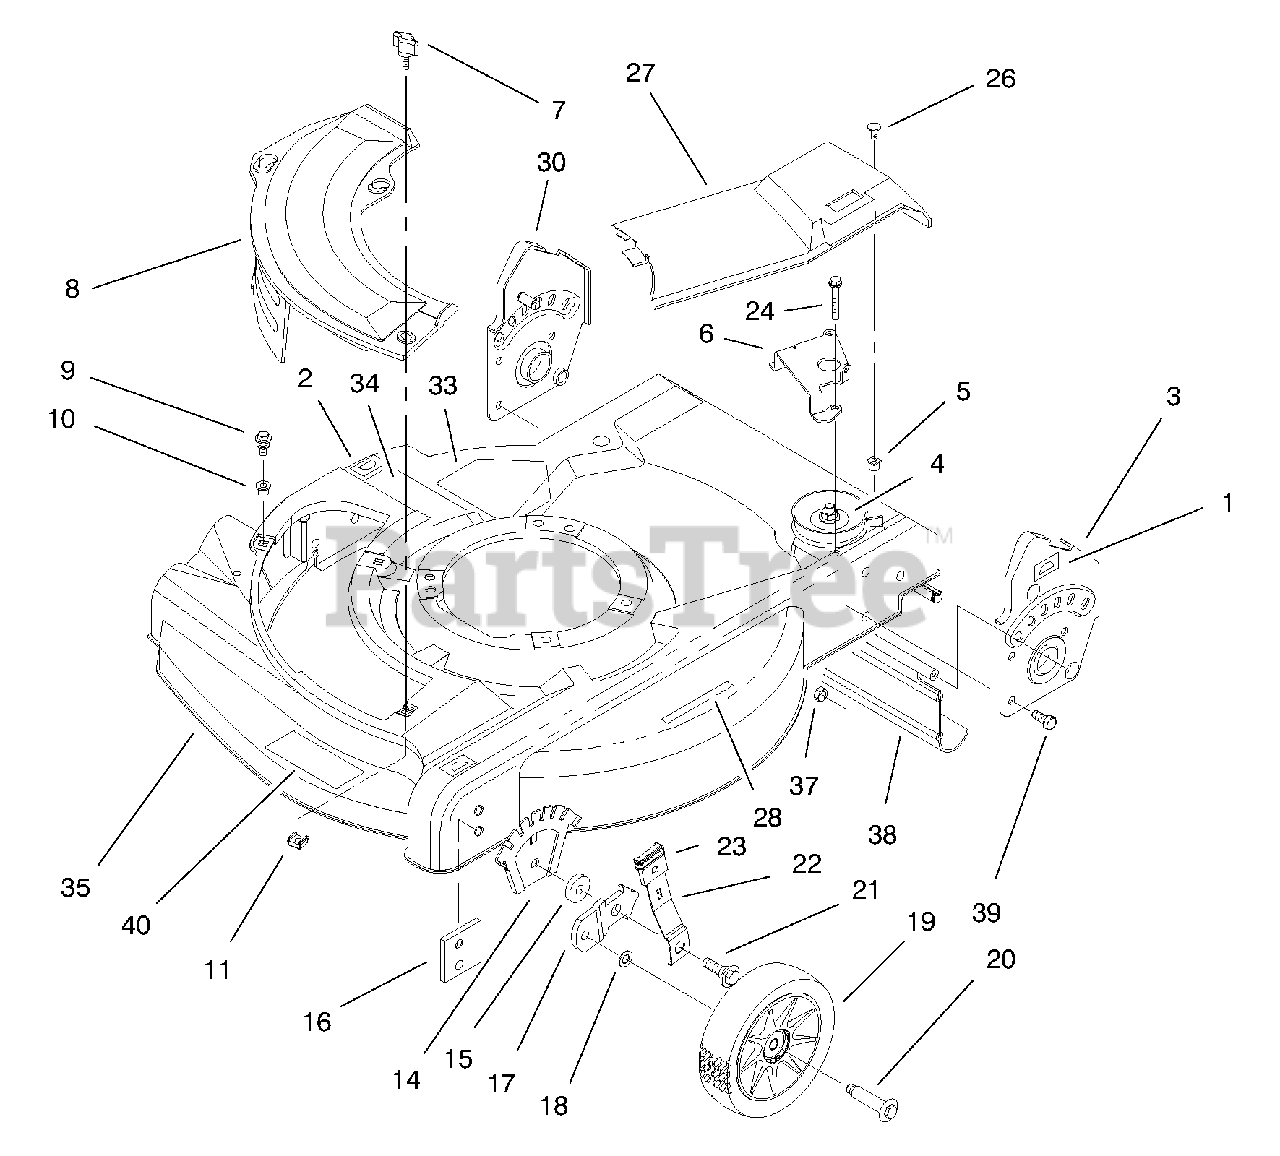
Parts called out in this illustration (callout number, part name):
1	Decal-HOC
2	Decal-HOC
3	ASM-Handle Bracket
4	ASM-Gear Case
5	Grommet
6	Guide-Transmission
7	Knob-Cover Plate
8	Mulch Plate-21"
9	Screw-Sems
10	Grommet-Plastic
11	Nut-Cage
14	Plate-Height Adjust
16	Plate-Baffle
17	Bracket-Wheel Height Adj
19	ASM-Wheel & Tire 6"
20	Bolt-Shoulder
21	Bolt-Shoulder
22	Spring Arm-Front
23	Knob-Height Adjust
24	Screw-HH
26	Screw-Phil
27	Cover-Drive
28	Decal-Warning
30	ASM-Handle Bracket
33	Decal-Danger
34	Decal-Discharge
35	ASM-Housing & Baffle
37	Nut-Lock
38	Shield-Trailing
39	Screw-HH
40	Decal-Deck
